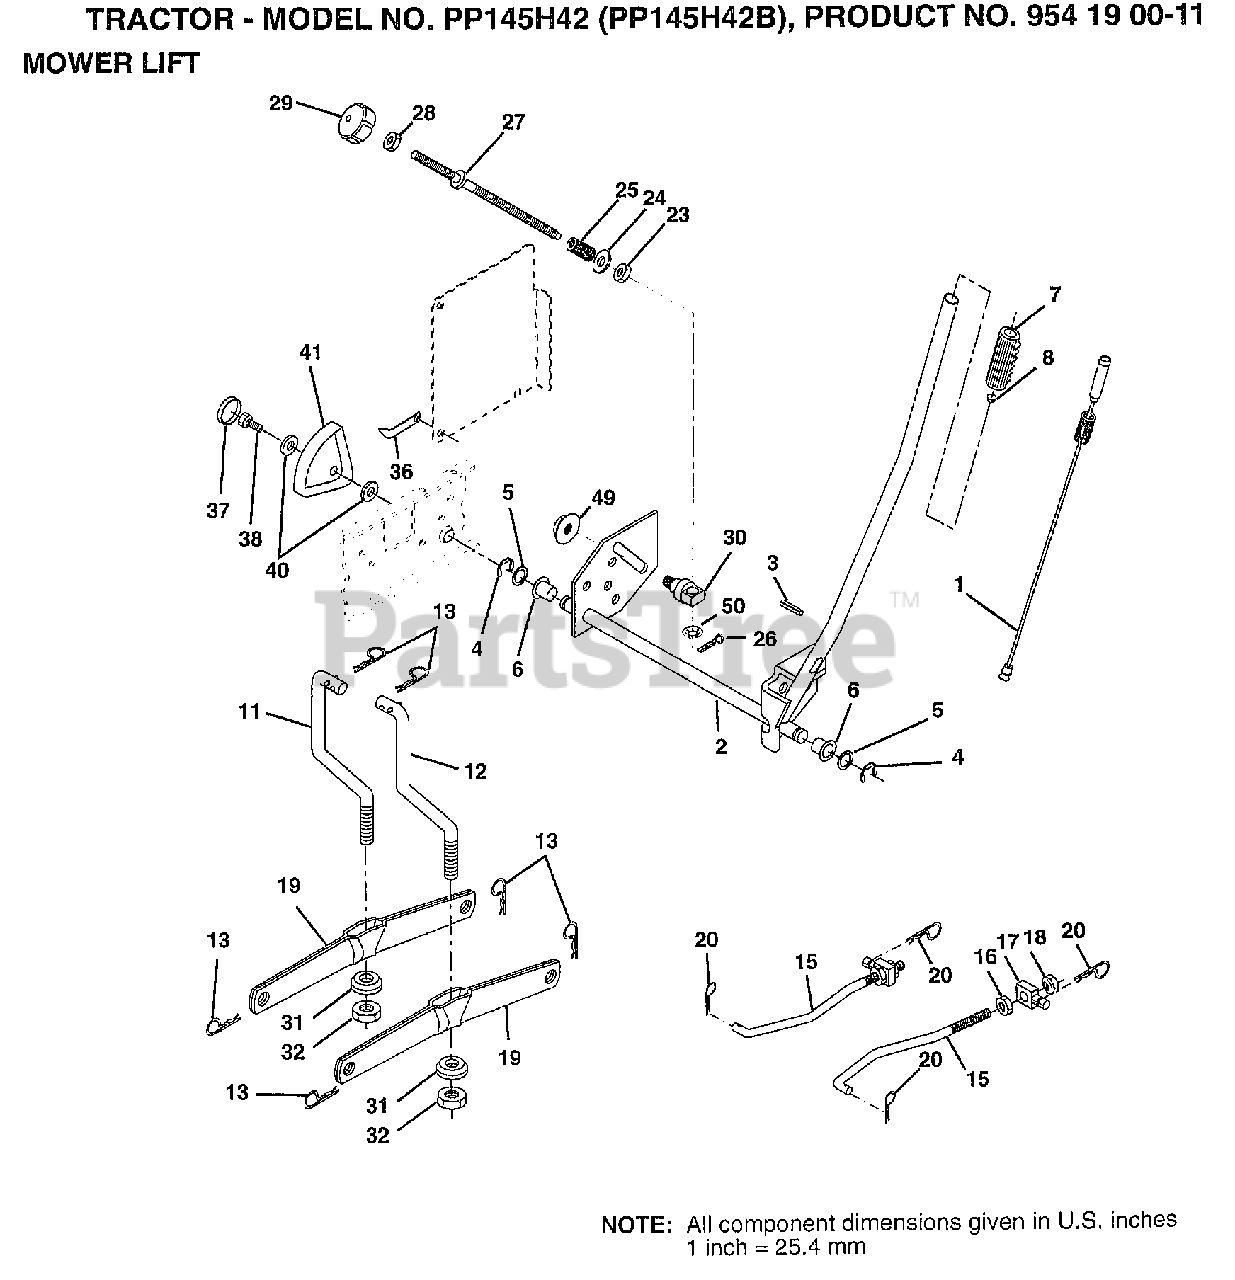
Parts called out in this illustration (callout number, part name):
1	WIRE ASM W.SPRING
2	"SHAFT ASM LIFT,RH"
3	PIN-GROOVE LT
5	WASHER
6	NYLON BEARING
7	GRIP
15	LINK.FRONT
16	NUT
17	TRUNION
18	NUT.LK.W/WSH.1/2.
19	ARM SUSP REAR
20	RETAINER.SPRING
23	NUT T
24	WASHER
25	SPRING T
28	NUT
29	KNOB INF 3/8-16
30	TRUNNION
31	BEARING PVT LH
32	NUT.CROWNLOCK.3/8
36	POINTER-INDICAT
37	"PLUG,HOLE"
38	SCREW
40	WASHER
41	HEIGHT INDICATOR
49	NUT.HXFLG.LOCK.
50	NUT PUSH M
